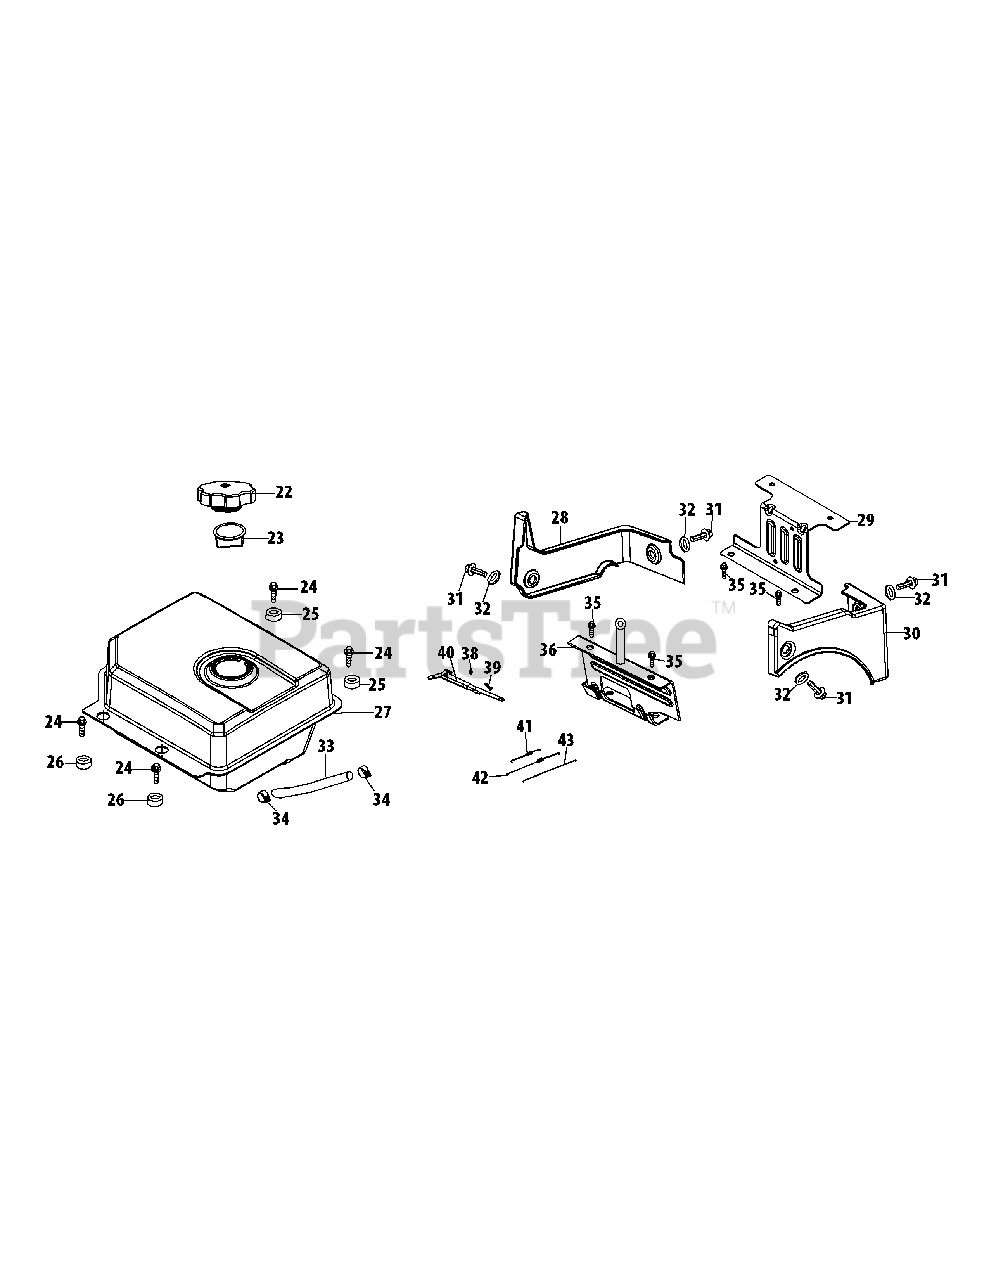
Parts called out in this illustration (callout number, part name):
22	Fuel Cap Assembly
23	Fuel Filter
24	Bolt M8×20
25	Bush I, Gas Tank
26	Bush II, Gas Tank
27	Fuel Tank Assembly
28	Left Trim Plate
29	Rear Mainting Bracket Assy.
30	Right Trim Plate
31	Bolt M6×16
33	Fuel Line Kit
34	Fuel Hose Clamp
35	Bolt M8×14
36	Gas Tank Support Bracket
38	Nut M6
39	Governor Arm Bolt
40	Governor Arm
41	Governor Spring
42	Throttle Linkage Spring
43	Throttle Linkage
